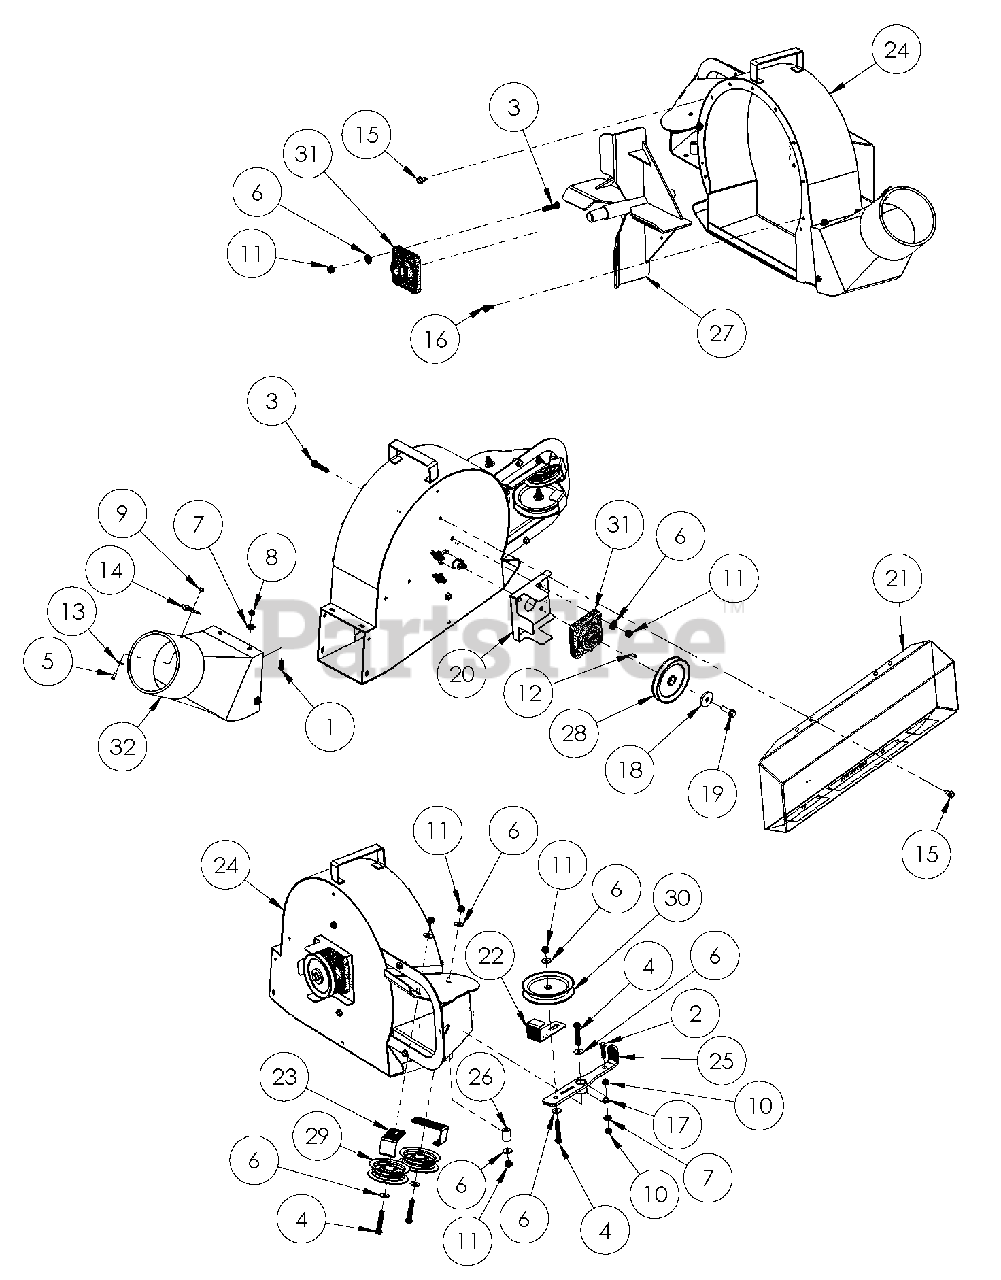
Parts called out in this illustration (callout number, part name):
1	Cap Screw 1/4-20 X .75
2	CS 5/16-18 X 1 1/4 G5
3	Cap Screw 3/8-16 X 1.50
4	Cap Screw 3/8-16 X 2.00
5	#10 X 1/2" Screw
6	5/16" Flat Washer
7	1/4" USS Washer
8	1/4-20 Nylon Insert Nut
9	#10-24 Nylon Insert Nut
10	5/16-18 Nylon Insert Nut
11	3/8-16 Nylon Insert Nut
12	Key 3/16 Sq X .50
13	#10 Fender Washer
14	Spring Clip
15	5/16 X 5/8" Selt Tap Screw
16	Selt-Tapping Screw 5/16 - .750
17	Belt Drive Tension Spring
18	Flat Washer, .39 ID X 1.5 OD X .188", YZ
19	Cap Screw Serrated Flange 3/8-16 X 1.25
20	Driven Belt Guide
21	Pulley/ Belt Cover
22	Large Idler Belt Guide
23	Belt Guide (Small Idler)
24	Vertical Blower Housing
25	Idler W/A
26	Idler Bushing
27	18" Bent Blade Impeller
28	Pulley, 4 1/2" A, 3/4" ID
29	Idler Pulley, 3" High Flange, 3/8" ID
30	5" 'V' Groove Idler
31	SQT Pillowblock BRG 1.0" I.D.
32	Transition Chute - Revised
